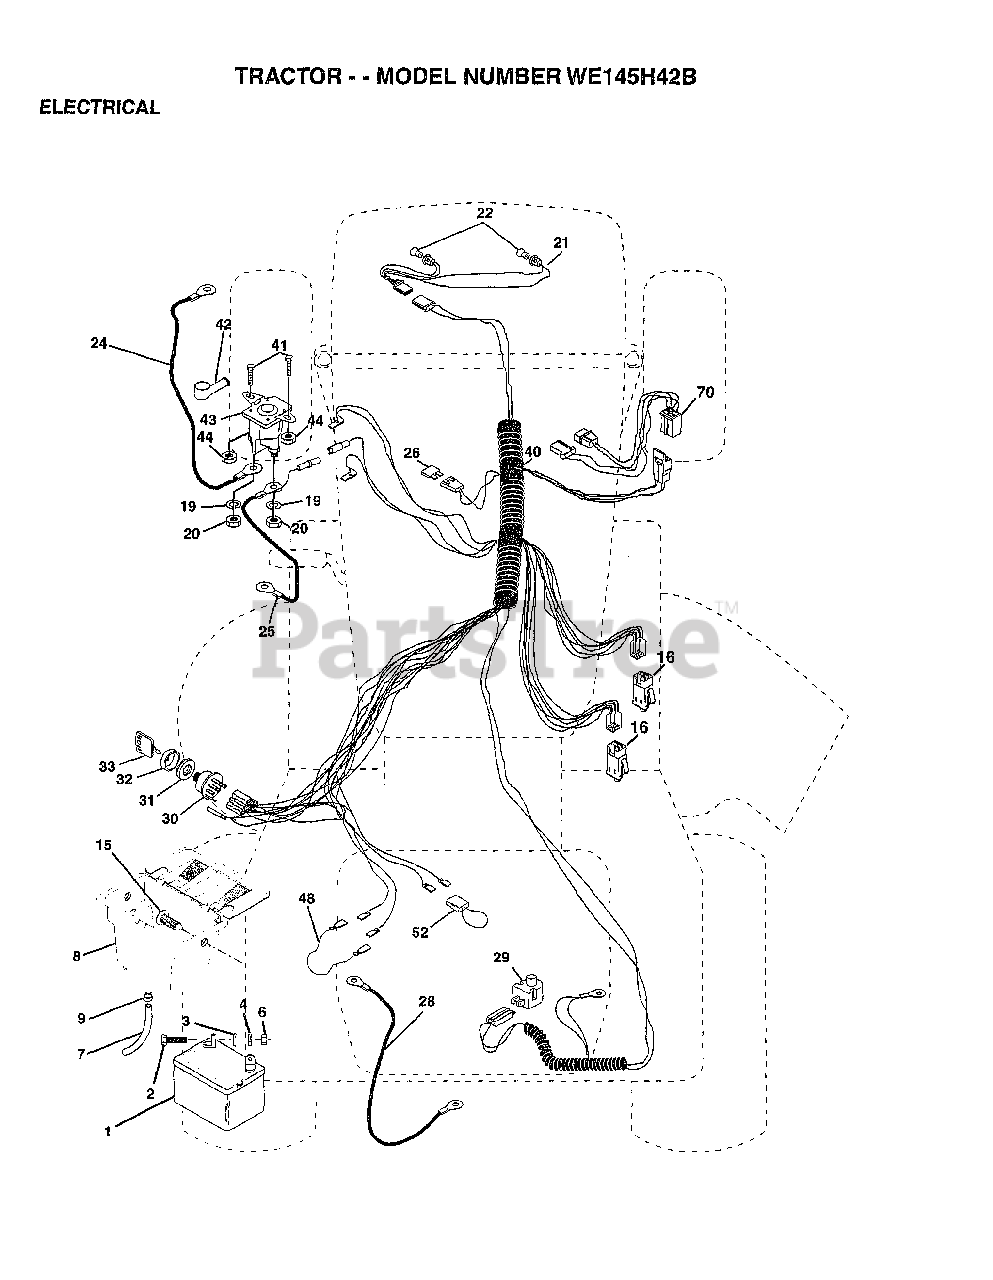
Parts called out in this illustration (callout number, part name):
2	BOLT LT
3	WASHER
4	LOCKWASHER
7	TUBE T
8	"CASE,BATTERY.MECH"
9	HOSE CLAMP T
15	FASTNER.SNAP-IN
16	SWITCH INTERLOCK
20	NUT
21	"HARNESS,LIGHT SOC"
22	HEADLAMP BULB
24	"CABLE T, BATTERY"
25	CABLE.BTRY.6GA.RD
26	FUSE HYT
28	CABLE T
29	SWITCH SEAT
30	SWITCH IGN 4POS
31	NUT IGNITION
32	COVER KEY SWITCH
33	KEY
40	HARNESS-IGNITION
41	BOLT HXHD FIN
44	NUT HXKEP 1/4X20
48	ADAPTER AMMETER
52	PROTECTION LOOP
70	HARNESS.ENG.DUAL
